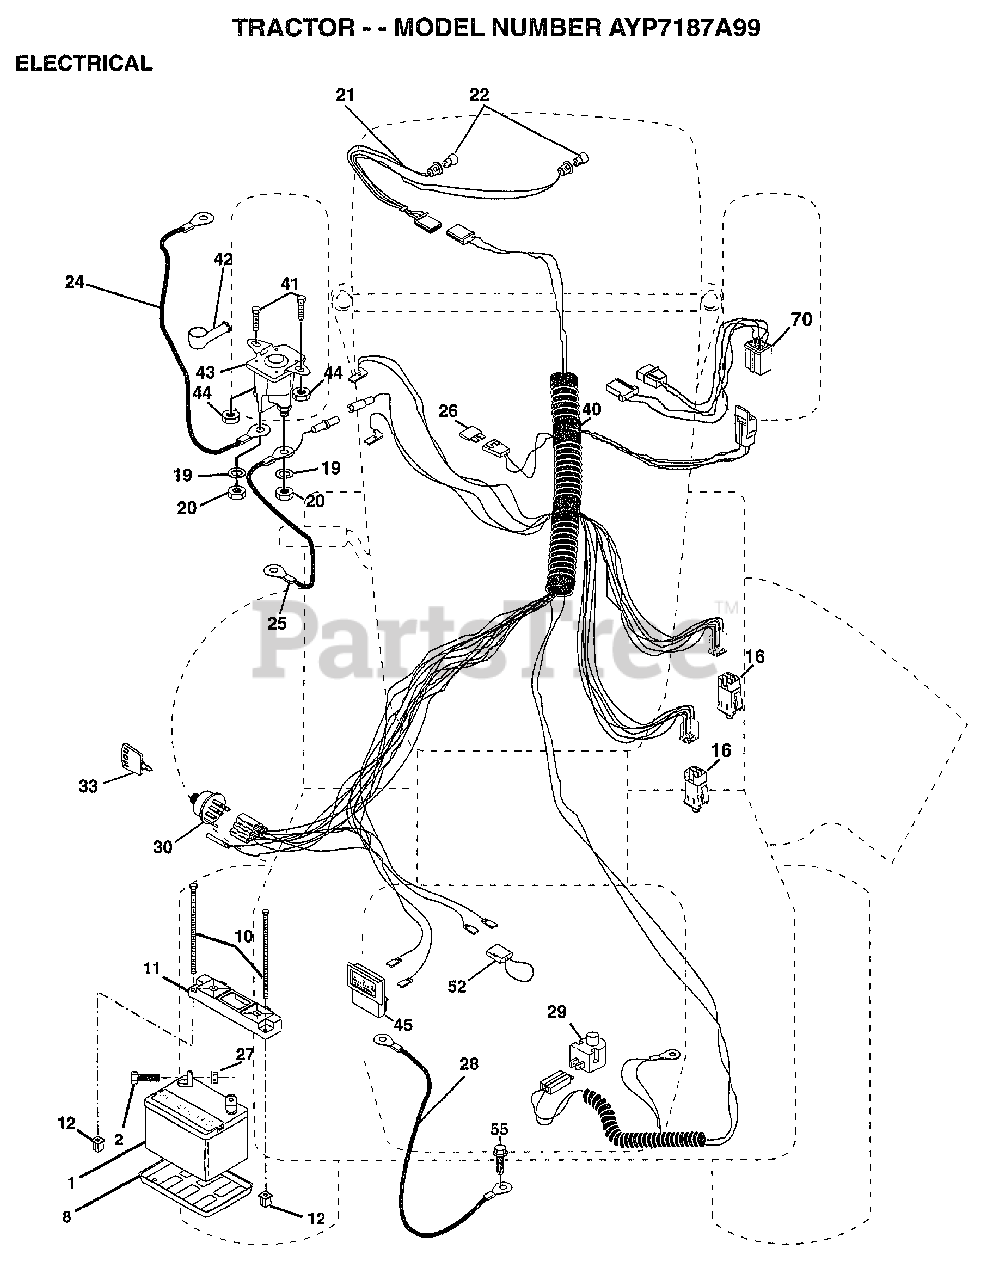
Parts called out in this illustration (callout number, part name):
2	BOLT LT
8	"TRAY T, BATTERY"
11	HOLDDOWN BATTERY
16	SWITCH INTERLOCK
20	NUT
21	"HARNESS,LIGHT SOC"
22	HEADLAMP BULB
24	"CABLE T, BATTERY"
25	CABLE.6GA.22W/16W
26	FUSE.15 AMP
27	NUT
28	CABLE.GRND.6GA.21
29	SWITCH SEAT
30	SWITCH IGN 4POS
31	NUT IGNITION
32	COVER KEY SWITCH
33	KEY
40	HARNESS.IGNITION
41	BOLT HXHD FIN
44	NUT HXKEP 1/4X20
52	PROTECTION LOOP
55	SCREW LT
70	HARNESS.ENGINE.B&S
